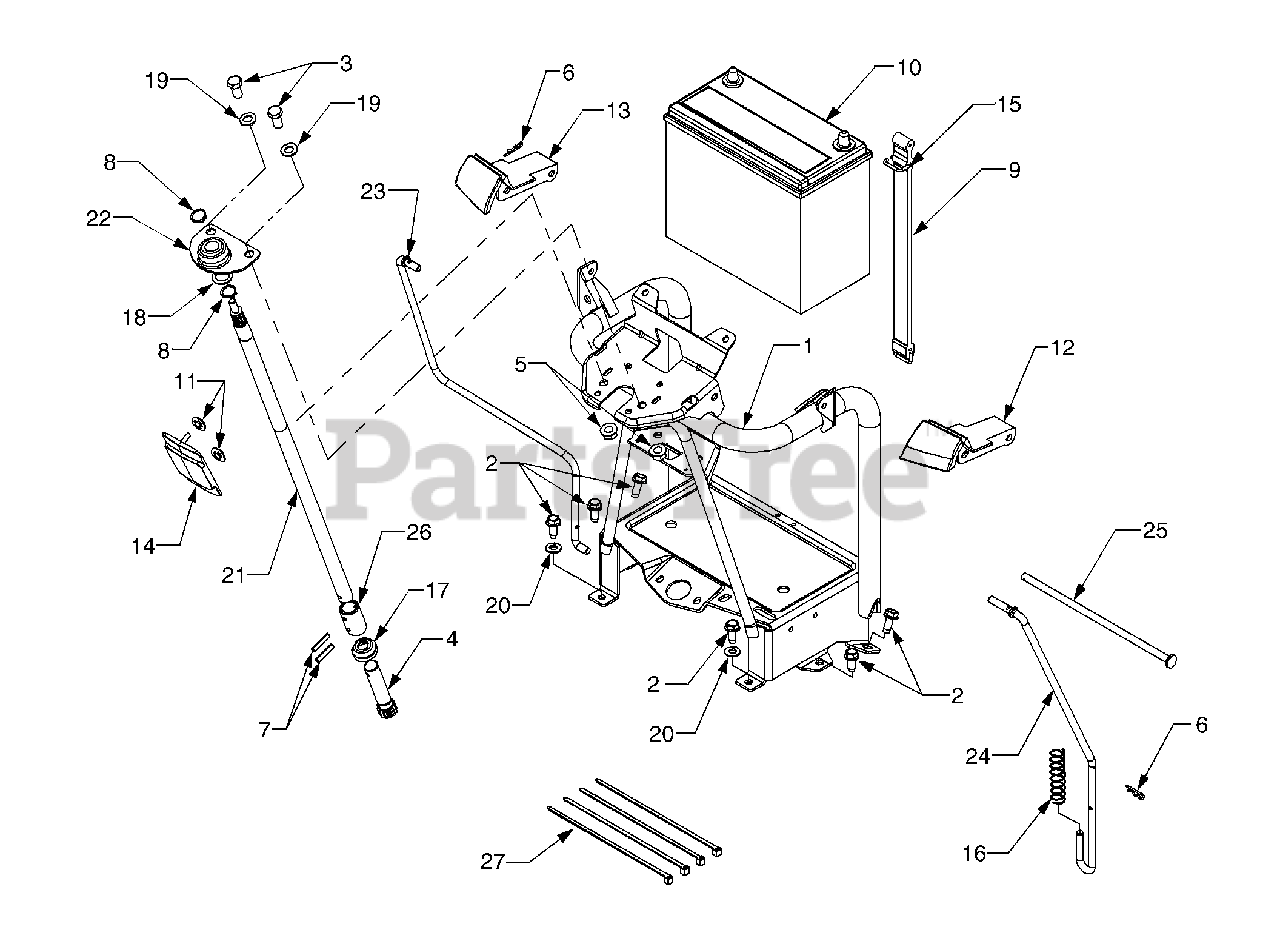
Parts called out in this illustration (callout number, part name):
1	Pedestal Assembly
2	Screw, Hex Wash. Hd. Tapp 5/16-18 x .75
3	Screw, Hex Cap 3/8-16 x .75 GR5
4	Shaft, Lower Steering
5	Nut, Hex Flange Lock, 3/8-16
6	Pin, Internal Cotter
7	Pin, Spirol, 3/16 x 1.0
8	Ring, Retaining, .56 Dia Shaft
9	Strap, Battery
10	Battery
11	Push Nut, .188 Dia.
12	Lever, Park Brake
13	Lever, Cruise
14	Cover, Fixed Steering
15	Hook, Wire Rectangular
16	Spring, Compression, .676 x 2.57
17	Boot, Shaft Cover
18	Washer, Flat, .635 x .93 x .06
19	Washer, Flat, .375 x .738 x .063
20	Washer, Flat, .344 x .688 x .065
21	Shaft, Upper Steering
22	Bearing, Steering Support
23	Rod, Cruise Control
24	Rod, Parking Brake
25	Rod, Cruise/Brake Pivot
26	Sleeve, Fixed Steering
27	Cable Tie, Harness
